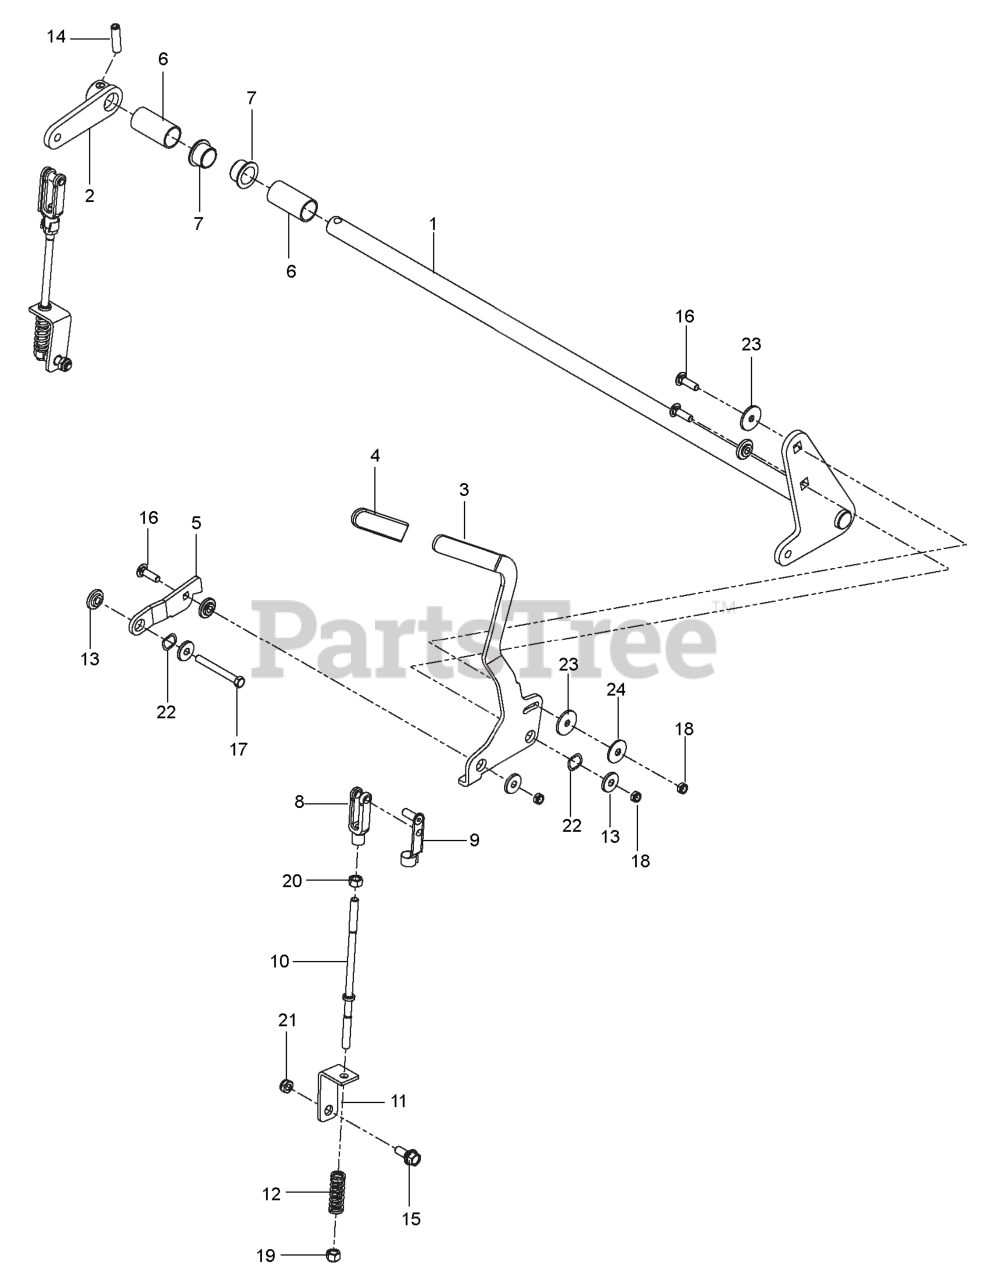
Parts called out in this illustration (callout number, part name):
1	SHAFT, BRAKE, WELDED
2	ARM, BRAKE, RT
3	LEVER.BRAKE.BLACK
5	LINK, FOLLOWER
6	SPACER, SHAFT, BRAKE
7	BEARING, FLANGE
8	YOKE 5/16 ADJ CLEVIS
9	PIN, CLEVIS SPRING 5/16
10	LINKAGE, BRAKE
11	BRKT, BRAKE, BLK
12	SPRING, ENGAGEMENT
13	BUSHING, BRAKE
14	5/16 DIA ROLL PIN
15	BOLT, SHOULDER
16	RHSNB 3/8-16 X 1-1/4
17	HCS 3/8-16 X 3-1/4 GR5 ZD
18	NUT HEX 3/8-16 NYLON, THIN
19	NUT 5/16F NYLOC
21	5/16-18 THIN PROF NY
22	WASHER, .825 X 1.087, WAVE
23	WASHER, FRICTION, 1/8
24	CONE WASHER
